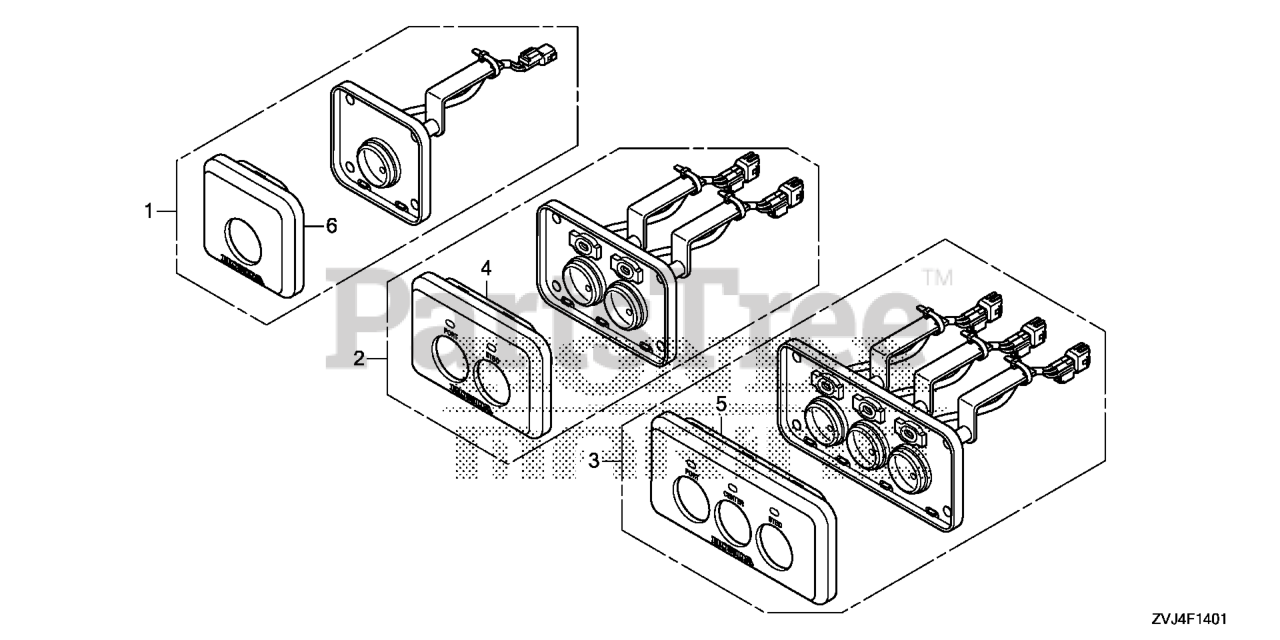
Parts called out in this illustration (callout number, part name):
1	PANEL ASSY., START STOP (ALL)
3	PANEL ASSY., START STOP (TRIPLE)
5	PANEL, START STOP (TRIPLE)
6	PANEL, START STOP (ALL)
